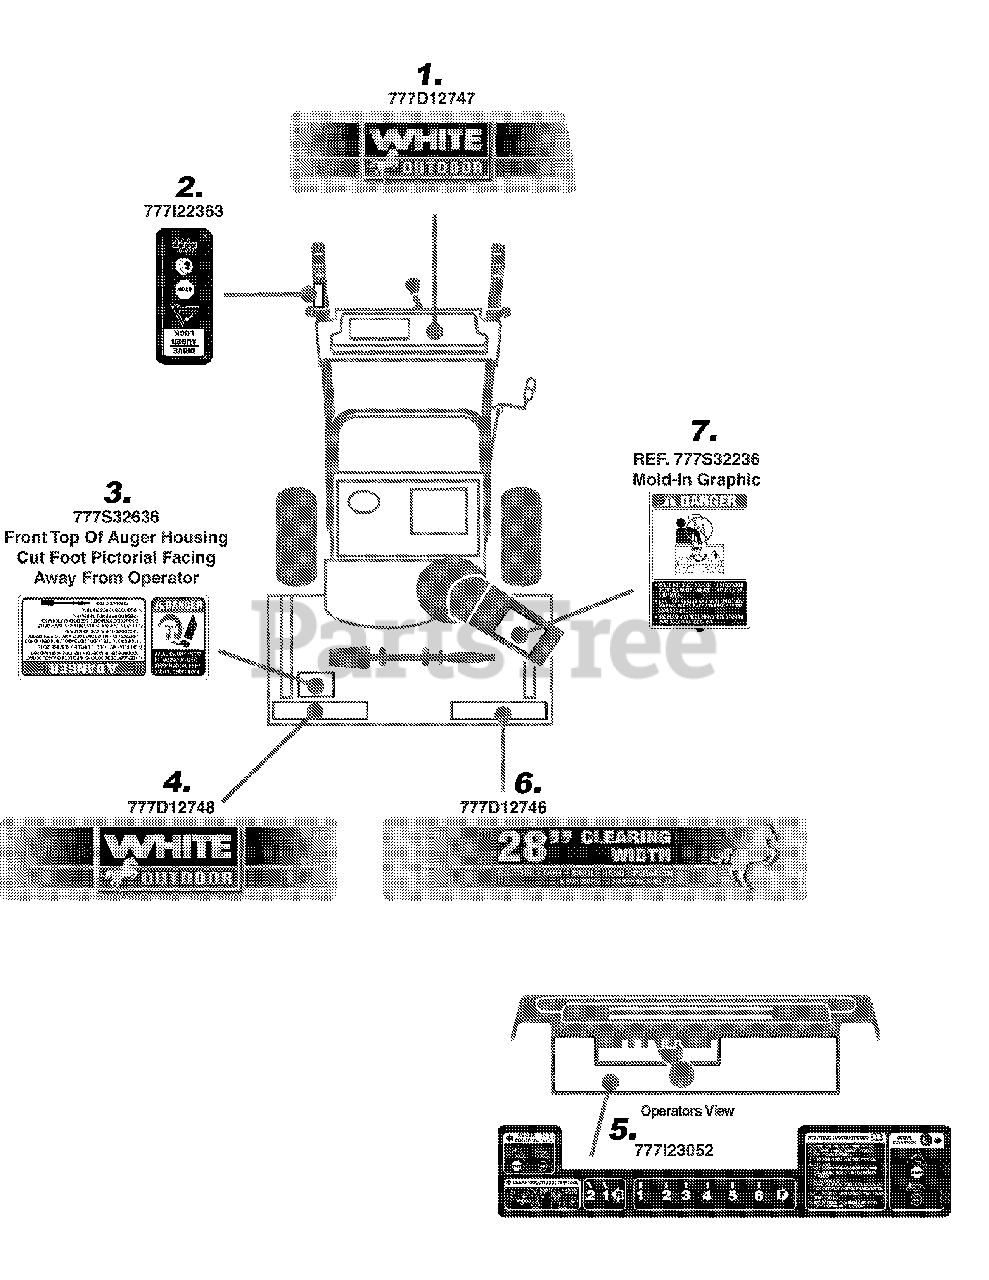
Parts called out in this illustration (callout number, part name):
1	LABEL-SNOW:F PNL:WHITE
2	LABEL-DRV/AUGR LOCK
3	LABEL-SNOW HOUSING
4	LABEL-SNOW:HSG:WHITE LOGO
5	LABEL-SNOW E,F PANEL
6	LABEL-SNOW:HSG:WHITE 28"
7	LABEL-SNOW CHUTE
